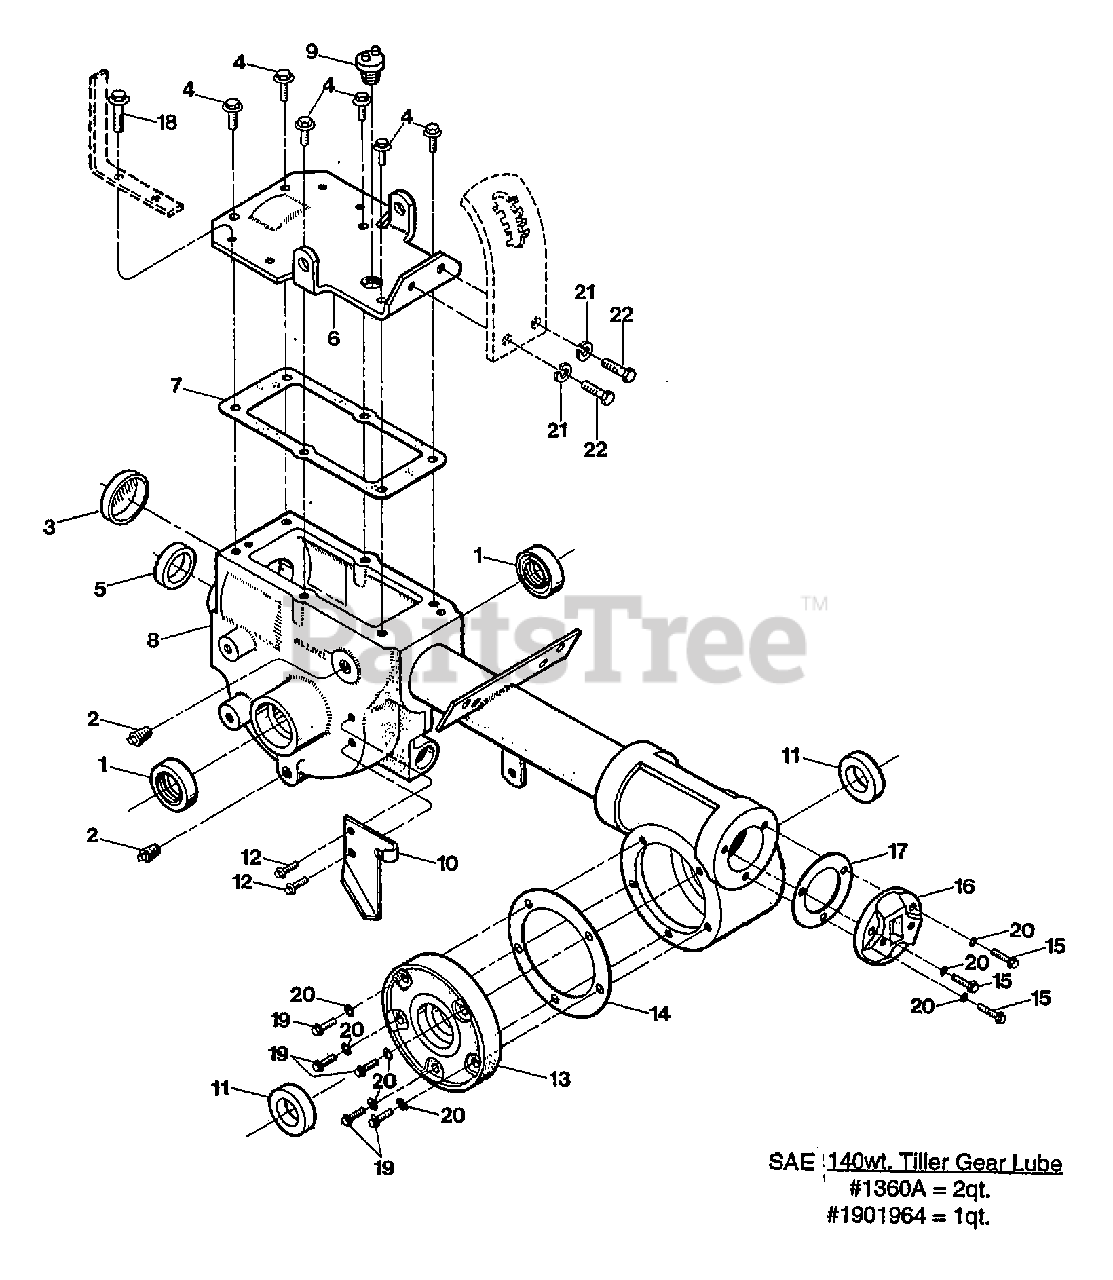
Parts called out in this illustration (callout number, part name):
1	SEAL-OIL WHEELSHAFT
2	PLUG-PIPE 1/4 NPT
3	SEAL-BORE
4	SCR-HFLK 5/16-18X.75
5	SEAL-PINION SHAFT PT/85030/00
6	KIT-COVER TRANS W/HDW (INCL. FOUR #18 & TWO EA. # 21 & 22)
7	GASKET-TRANS COVER
8	ASSM-TRANS A-UNIT P/ECHO
9	PLUG-OIL FILL 3/4-10
10	PLATE-CABLE MT PNT
11	SEAL-TILLER SHAFT
12	SCR-HFLK 5/16-18X.62 G5
13	COVER-TILLER HSG MACH (INCL. 5 #19)
14	GASKET-TILLER COVER (FITS ALL COVERS)
15	KIT-SEALING SCRS (3)
16	CAP-REAR #1115
17	GASKET-BRG COVER
18	SCR-HFLK 5/16-18X1.00
19	SCR-HXSKT 1/4-20X.625
20	ITEM NO LONGER USED
21	WASHER-LK .375
22	SCR-HH 3/8-16X.75 G5
